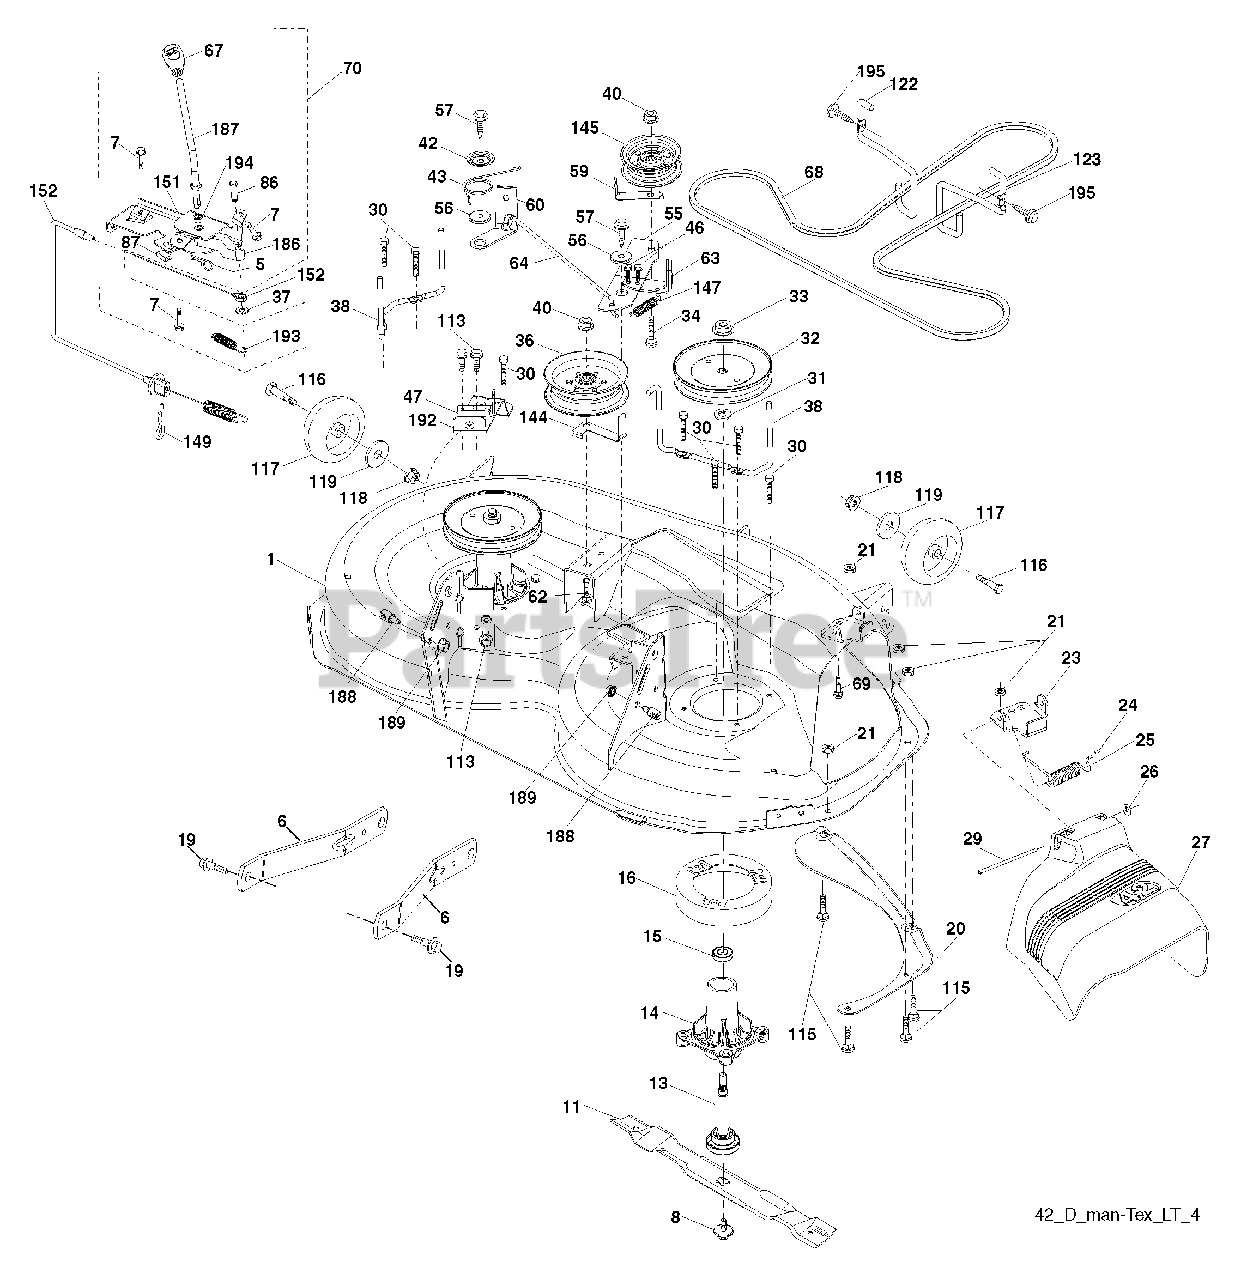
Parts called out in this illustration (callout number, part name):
1	Deck Weldment Mower
5	Retainer Spring
6	Arm Suspension
7	Screw 10 x 3/4 Single Lead Hex
8	Bolt/Washer asm 7/16-20 unf
11	Blade, 42" Hi-Lift (For bagging or discharge)
11	Blade, 42" Mulching Std (For mulching mowers only)
11	Blade, 42" Mulching Premium (For better wear when mulching)
13	Shaft Assembly, Mandrel
14	Housing, Mandrel
15	Bearing, Ball, Mandrel
16	Stripper, Mower Deck
19	Bolt, Shoulder
20	Baffl e, Vortex
21	Nut, Crownlock 5/16-18 unc
23	Bracket, Defl ector
24	Cap, Sleeve
25	Spring, Torsion, Defl ector
26	Nut, Push
27	Shield, Defl ector
29	Rod, Hinge
30	Screw Thdrol Rolling Wsh Hd
31	Washer, Spacer
32	Pulley, Mandrel
33	Nut, Toplock, Flanged
34	Bolt Carr Sh. 3/8-16 x 1-1/2 Gr. 5
36	Pulley, Idler, Flat
37	Washer
38	Keeper Belt LH Mandrel
40	Nut, Lock Flg. 3/8-16 unc
42	Spring Torsion Brake
43	Spring Torsion Retainer
46	Screw Thd Roll 1/4-20 x 5/8
47	Bracket Clutch Cable
54	Washer, Hardened
55	Arm, Idler
56	Spacer, Retainer
57	Screw 3/8-16 x 1
59	Guard, Tuv Idler
60	Arm Brake Mower
62	Bolt Rd Hd Sq Nk 3/8-16 unc x 2
63	Arm Brake Mower
64	Link Brake Asm
65	Spacer Retainer
67	Handle Clutch Cable
68	V-Belt
69	Bolt
70	Clutch Asm Manual
86	Pin Attachment Cable
87	Switch Interlock Clutch Cable
88	Screw 10-24 x 5/8
113	Bolt 5/16-18
115	Bolt Carr. 5/16-18 x 5/8
116	Bolt, Shoulder
117	Wheel, Gauge
118	Nut, Crownlock 3/8-1
119	Washer 13/32 x 7/8 x 14 Ga.
122	Keeper Belt Engine LH
123	Keeper Belt Engine RH
144	Keeper Belt
145	Pulley Idler
147	Spring Return
149	Retainer Spring
151	Bracket Clutch
152	Manual Clutch Cable
186	Arm Actuator
187	Lever Control
188	Stud Fastener
189	Nut Lock Hex Flange
192	Bracket Brake Stand LH
193	Spring Plunger Activator
194	Bearing Control Lever Clutch
195	Screw Hex Wsh THDR 3/8-16 x 3/4
195	Mandrel Assembly
195	Replacement Mower, Complete
